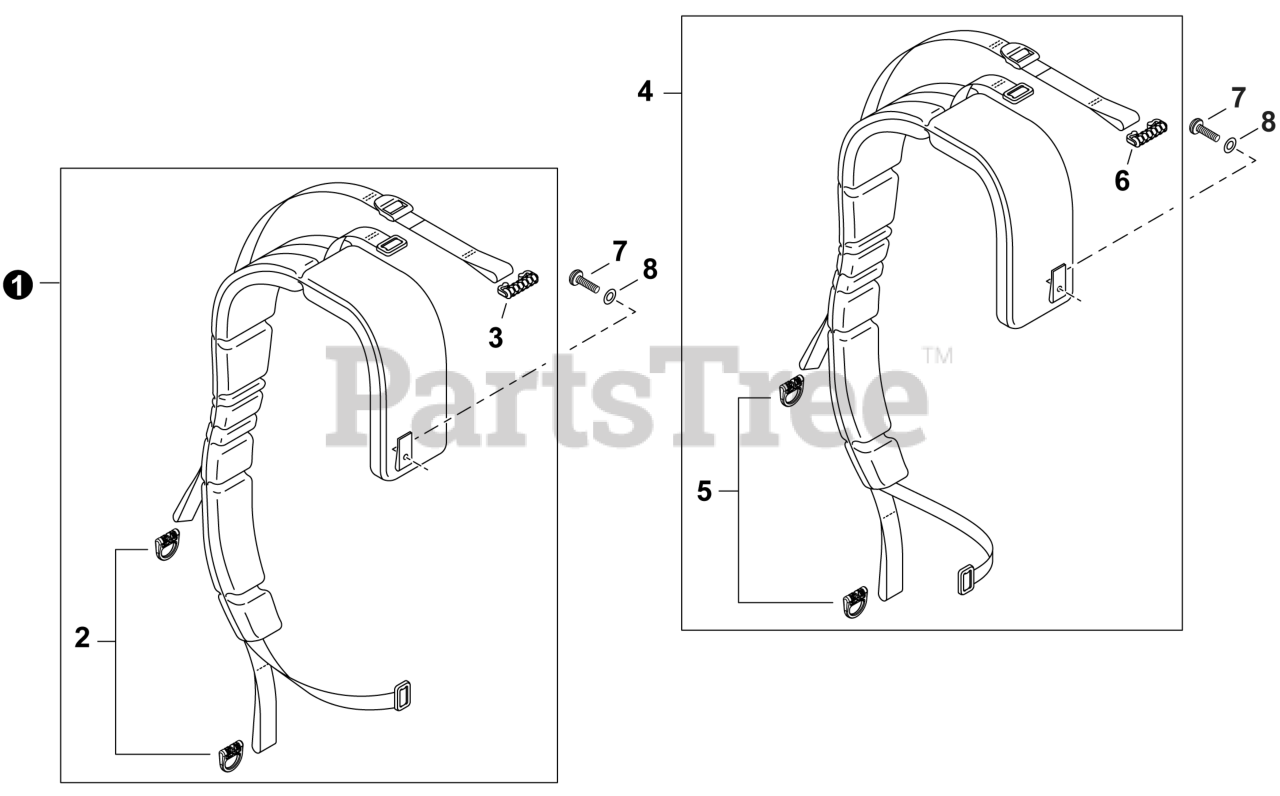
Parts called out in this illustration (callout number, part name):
1	HARNESS ASSY, LEFT
2	BUCKLE, HARNESS
4	HARNESS ASSY, RIGHT
5	BUCKLE, HARNESS
7	BOLT, TORX 5x20
8	WASHER 5.5x16x0.8
